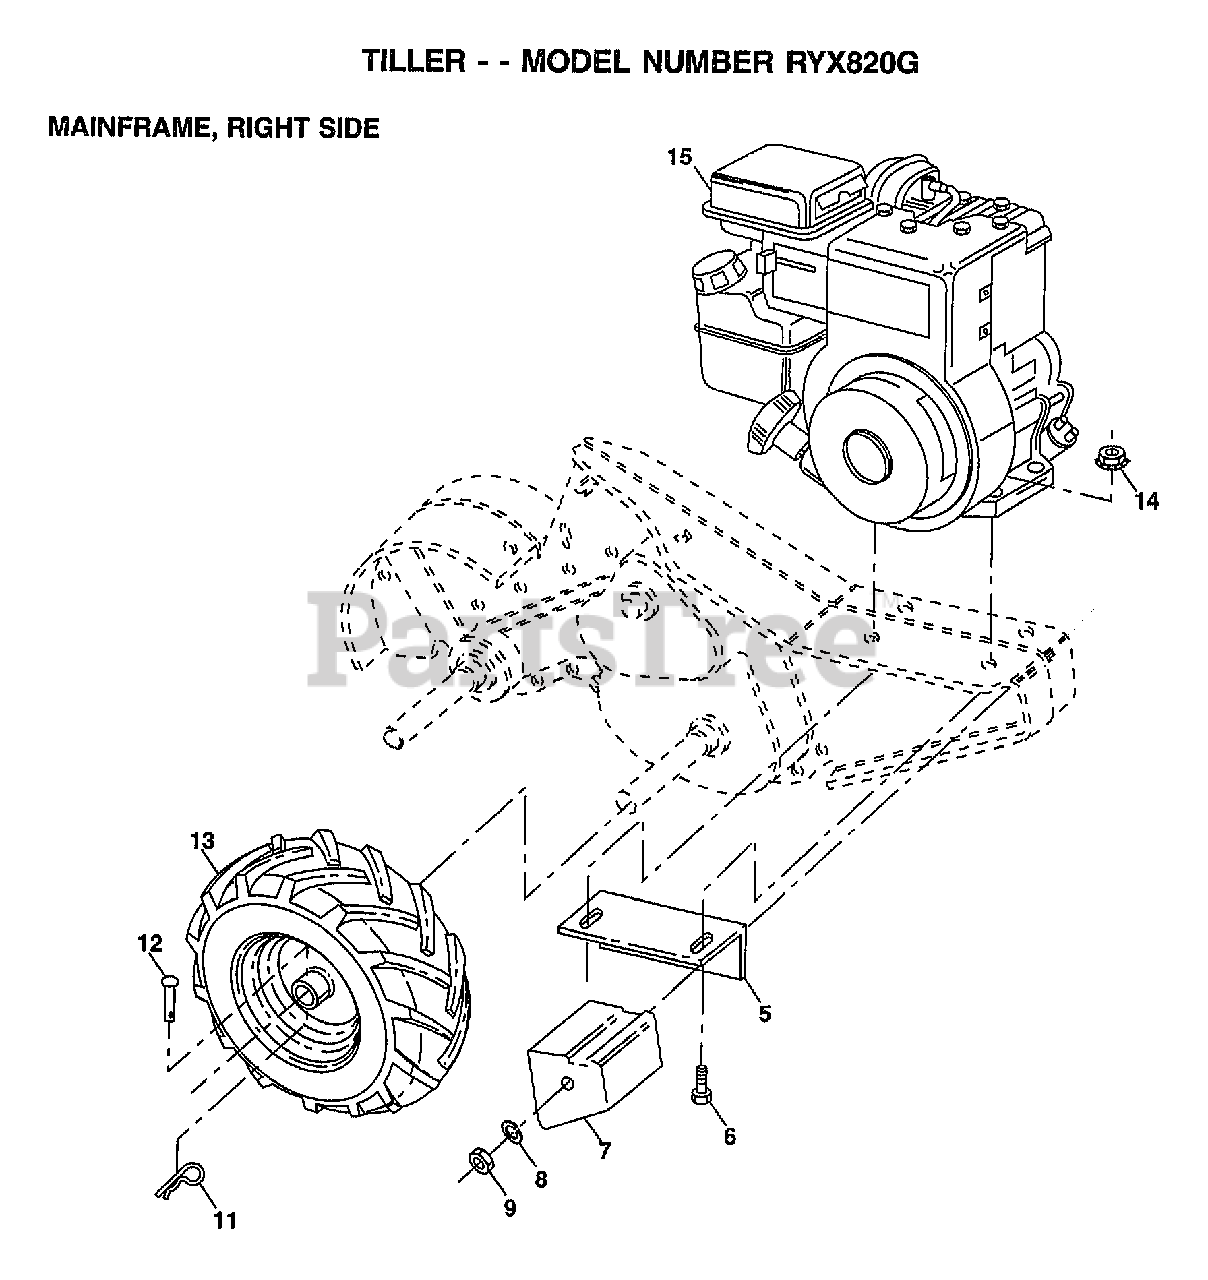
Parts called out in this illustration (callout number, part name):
5	BRACKET RH CRT
6	BOLT.HEX.5/16-1.5
7	COUNTERWEIGHT CRT
8	LOCKWASHER
9	NUT.HEX.3/8-16UNC
11	RETAINER M
12	RIVET.DRILL.1.75
13	TIRE.CHV.13X5.0-6
